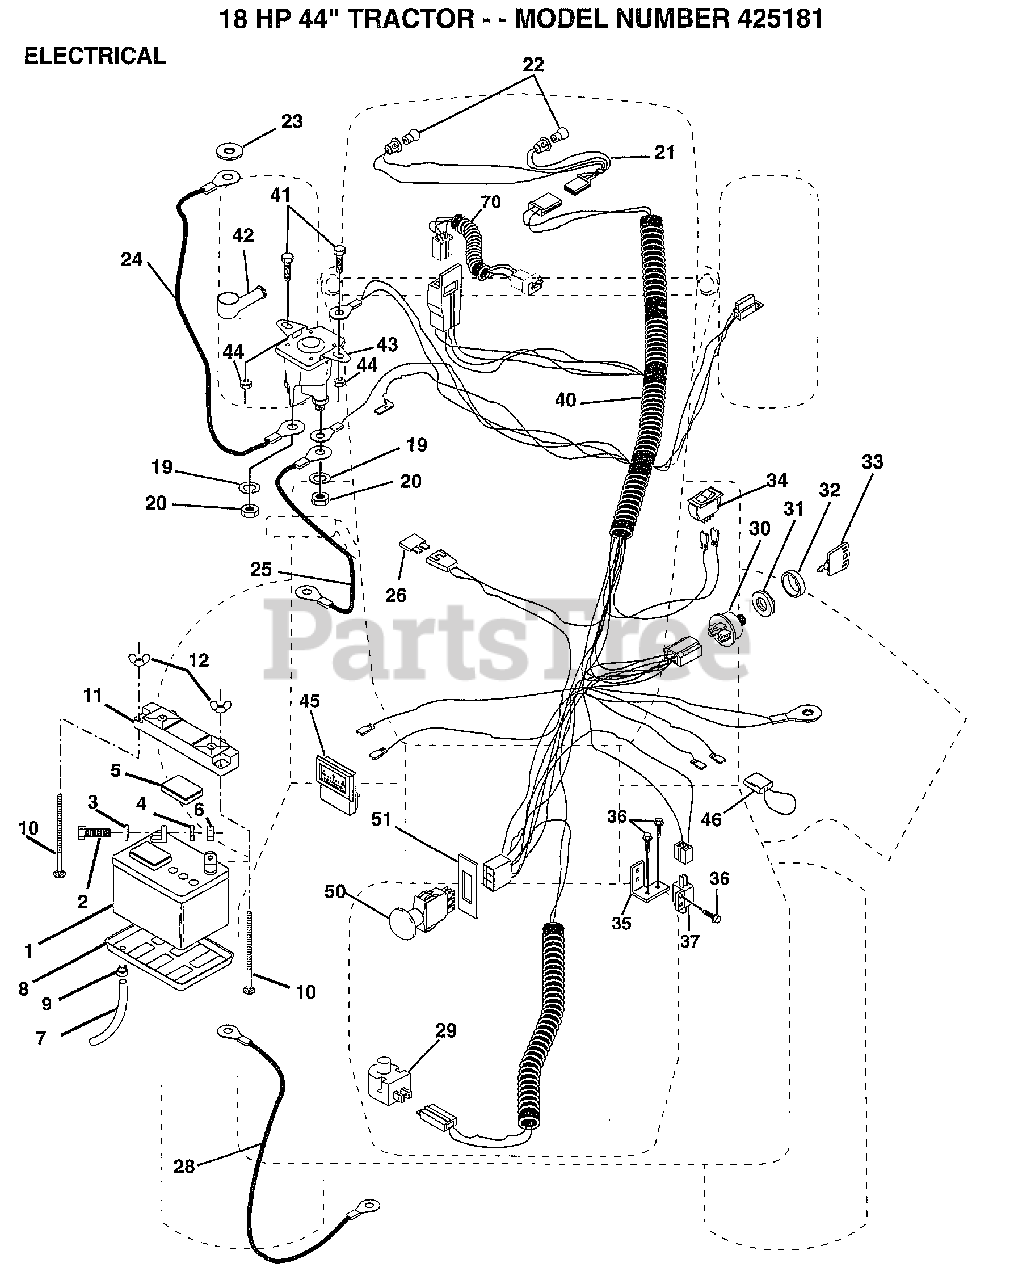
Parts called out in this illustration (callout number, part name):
2	BOLT LT
3	WASHER
4	LOCKWASHER
5	"CAP,BATTERY "
7	"DRAIN TU T, BATT"
8	"TRAY T, BATTERY"
9	HOSE CLAMP T
10	BOLT
20	NUT
21	"HARNESS,LIGHT SOC"
22	HEADLAMP BULB
23	LOCKWASHER
24	"CABLE T, BATTERY"
25	CABLE-BATTERY T
26	FUSE HYT
28	CABLE T
29	SWITCH SEAT
32	COVER KEY SWITCH
33	KEY MLD GEN DELTA
34	SWITCH LT
35	BRACKET LT
36	SCREW
37	SWITCH-INTER. GT
40	HARNESS IGNITION
41	BOLT HXHD FIN
44	NUT HXKEP 1/4X20
45	AMMETER
46	PROTECTION LOOP
51	RING RETAIN PTO
70	HARNESS.ENG.KOHL
